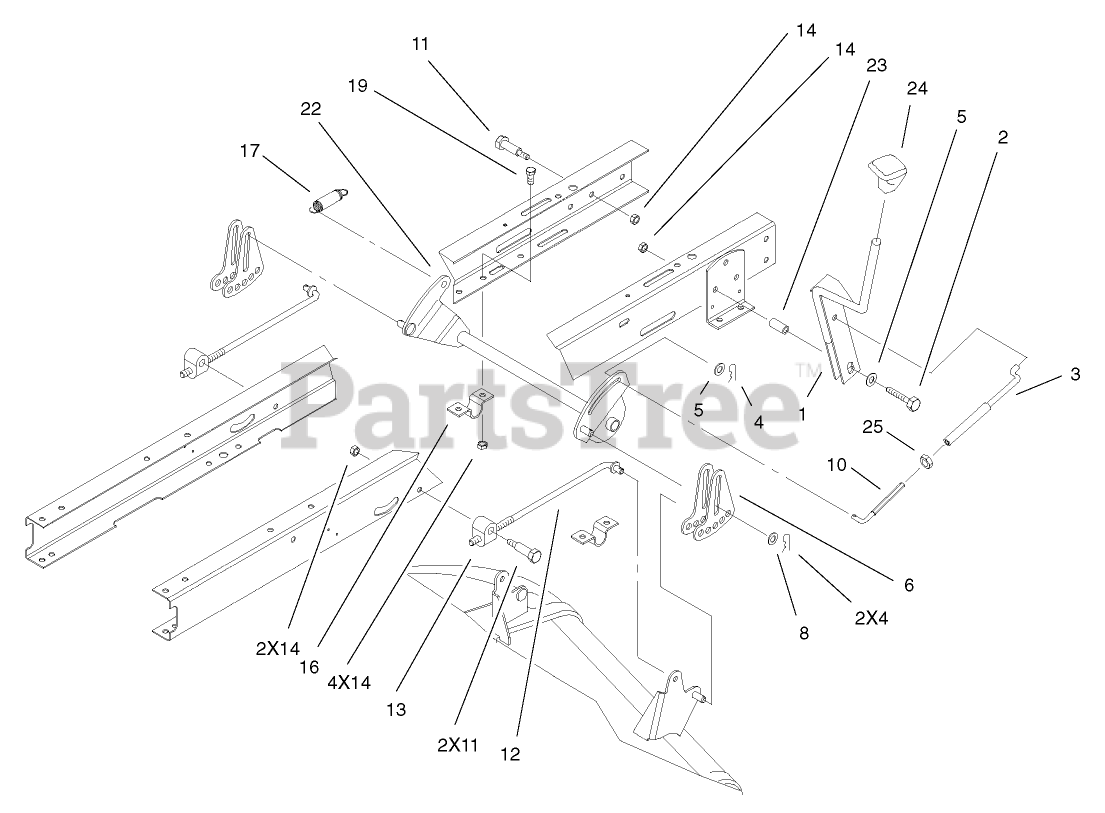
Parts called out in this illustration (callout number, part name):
2	SCREW-HH
3	HOC LINKAGE (WELDMENT)
5	WASHER-FLAT
6	LINK-ADJUSTING, HOC
8	WASHER-HARDENED
10	LINKAGE-HOC
11	SCREW-SHOULDER, HH
12	ROD-HANGER, REAR
13	TRUNNION-HOC
14	NUT-LOCK, NI
16	CLAMP-PIVOT, HOC
17	SPRING-EXTENSION
19	SCREW-HH
22	HOC PIVOT ASM (BLACK)
23	SPACER
24	KNOB-SHIFT
25	NUT-JAM
